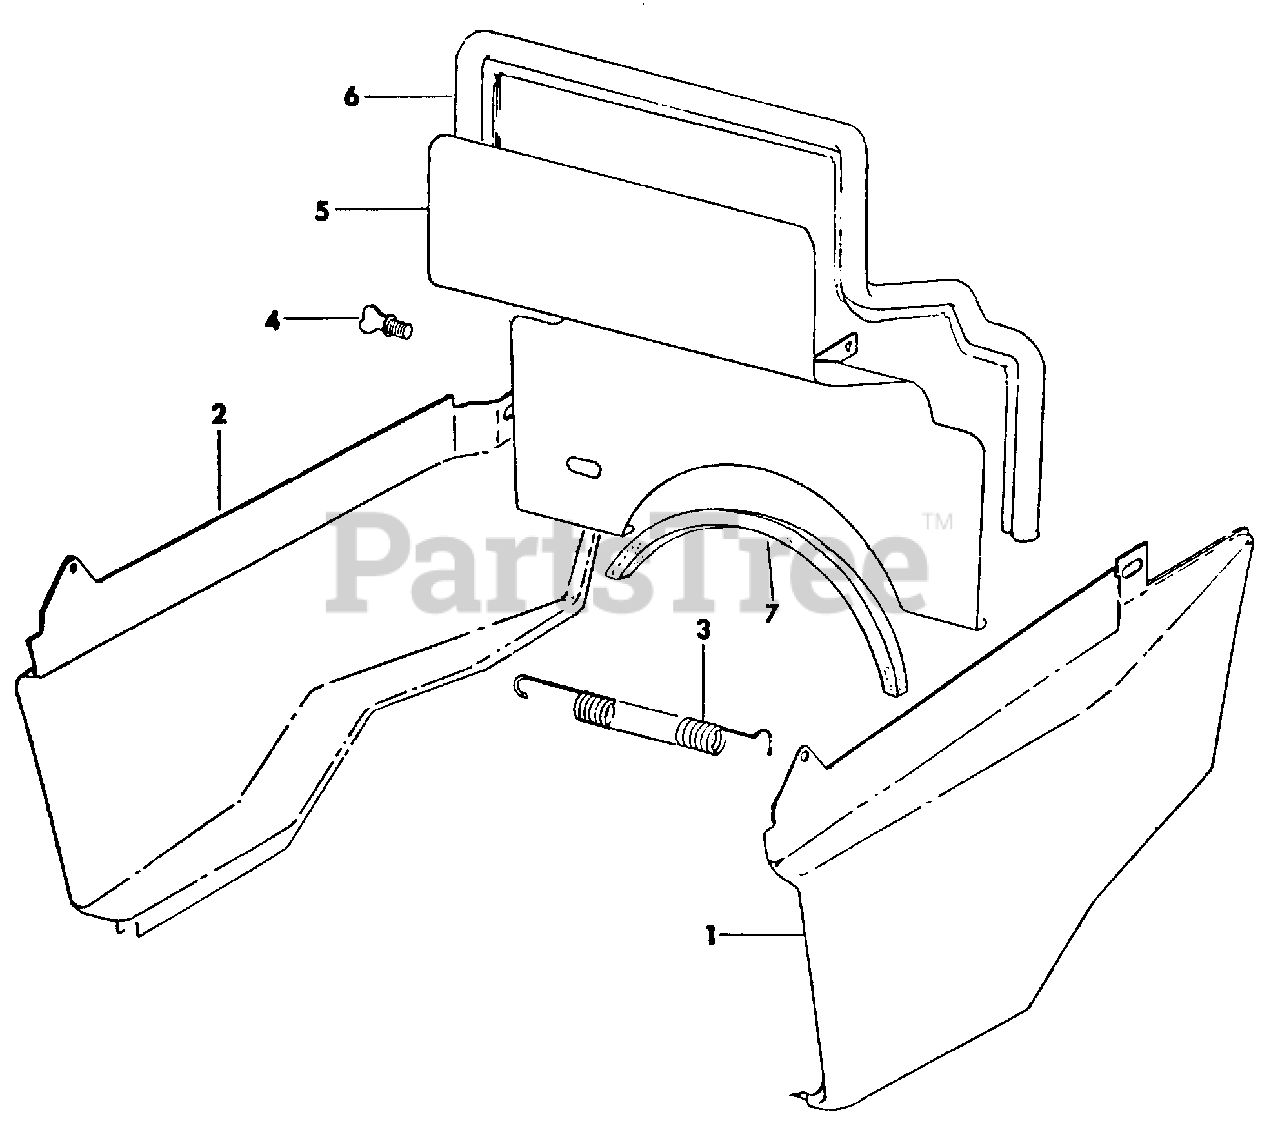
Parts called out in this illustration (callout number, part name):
1	Panel, LH Side
2	Panel, RH Side
3	Spring, Front
4	Screw, Thumb
5	Deflector Assy, Heat
6	Seal, Heat Baffle
7	Gasket, Foam
